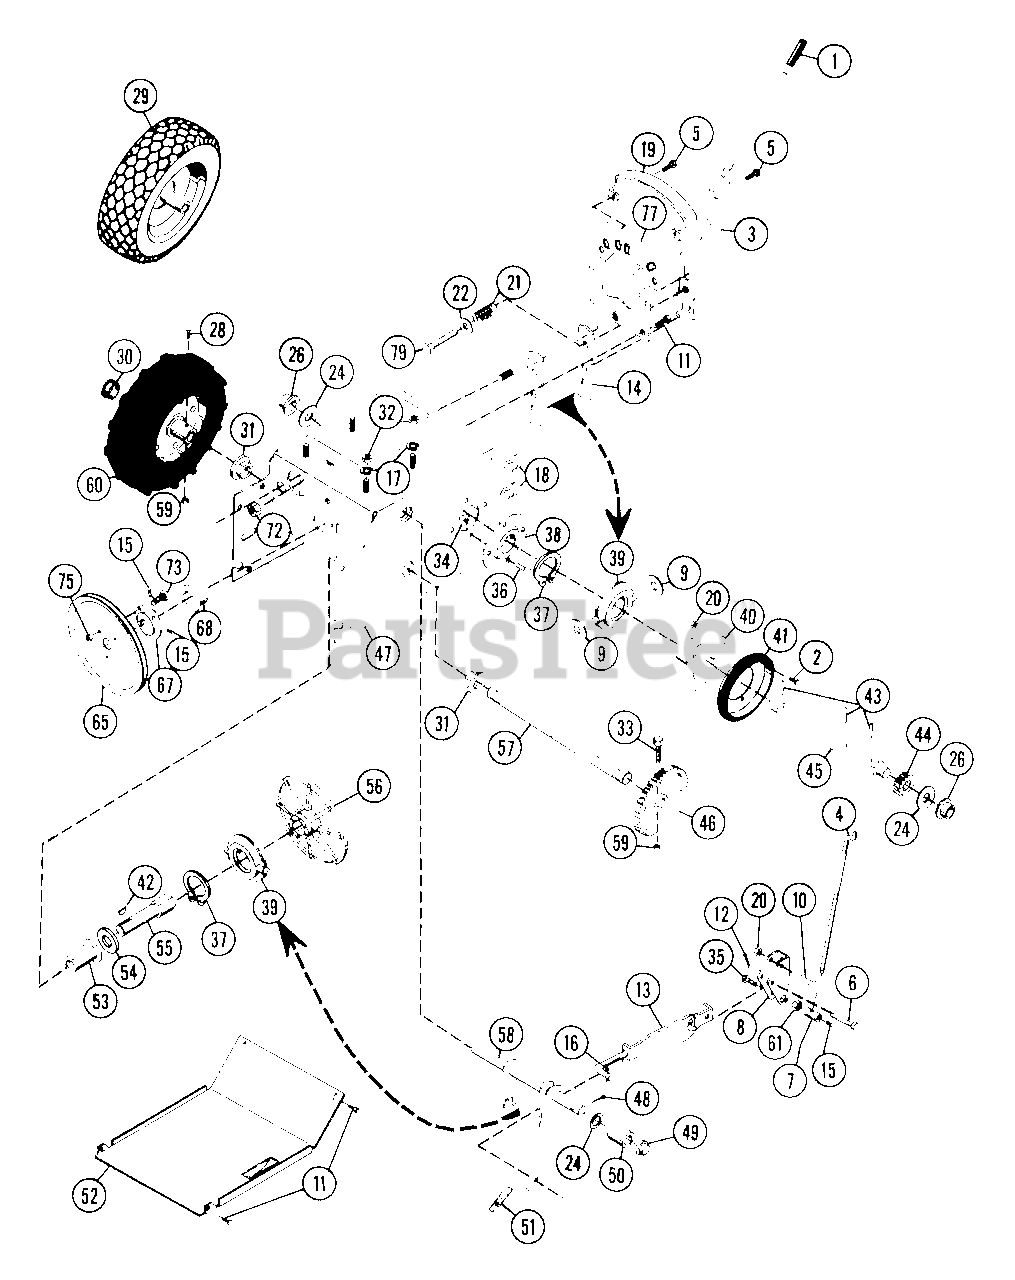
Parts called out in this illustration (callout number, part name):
1	GRIP 5/16 X 2 3/4
2	BLT-HEX .25-20X.50 PL GR2
3	SHIFT HANDLE
4	CLUTCH ROD
5	SCR-TAP 10-24X.375 HWH PL TR
6	CLEVIS PIN
7	ROD ADAPTER
8	BRACKET
9	WSHR-FL-STL .505X1.000X.062
10	BLT-HEX .25-20X1.75 PL GR2
11	BLT-SERHFWH .25-20X.50 PL
12	PIN-COTR .09X.75 PL
13	TRACTION CLUTCH ASSEMBLY
14	SHIFTING FORK
15	SCR-SET .32-18X.38 SKHCUPNL OH
16	PIN-HAIR INT .08X.18X1.18
17	WSHR-LK .312X.097 PL HVY
18	V-BELT, 3L-COGGED
19	SHIFT HANDLE RETAINER
20	NUT-LK-CTR .250-20 PL
21	SG-COMP .105X.585X.75
22	WSHR-FL-STL.344X.688X.065PL
24	WSHR-FL-STL .531X1.062X.095 PL
26	BSHG-FLG .500X.750X.625X.937
28	BLT-HEX .25-20X1.50 GR5
29	WHEEL ASSEMBLY
30	HOLE PLUG
31	BSHG-FLG.750X.875X.750X1.188HX
32	NUT-HEX .312-18
33	BLT-HEX .25-20X1.75 GR 8
34	NUT-LK DUAL FACE 10-24 PL
35	BLT-HEX .31-18X.75 PL GR2
36	BLT-RDHDSQNK 10-24X.38 PL
37	RG-RTNG-EXT 1.250X.050
38	BUSHING FLANGE
39	BEARING FLANGE
40	FRICTION WHEEL HUB
41	FRICTION DISC
42	KEY-WDRF .188X.75X.313 SAE 9
43	PIN-ROLL .125X.88
45	HEX SHAFT
46	GEAR ZYTEL
48	PIN-COTR .12X1.0 PL
49	CAP, .50 ROD YWZC
50	BSHG, SPCR.500X.750X.321 PM
51	SG-TENS .063X.44X1.56
52	BOTTOM COVER
53	BSHG-FLG .625X.875X1.750X1.188
54	WSHR, THRUST .625X1.125X.063
55	HEX SHAFT
56	FRICTION PLATE
57	AXLE SHAFT
58	CLUTCH FORK
59	NUT-LK TOP .250-20 PL
60	WHL
61	NUT-LK .312-18 GR A PL
65	PLY-V 8.0 X 1.25 3BLT SALEM
68	BSHG-FLG .875X1.25X.75X1.50HX
70	WSHR-FL-STL .38X.875X.083 PL
72	BSHG-FLG .750X1.000X.625X1.250
73	BLT-SERRDHD SL .31-18X.75 YZ
75	NUT-FLG. .312-18 PL
77	QUADRANT
78	NUT-RETNR .312-18 TINRMAN
79	BLT-HEX .31-18X1.50 PL GR2
